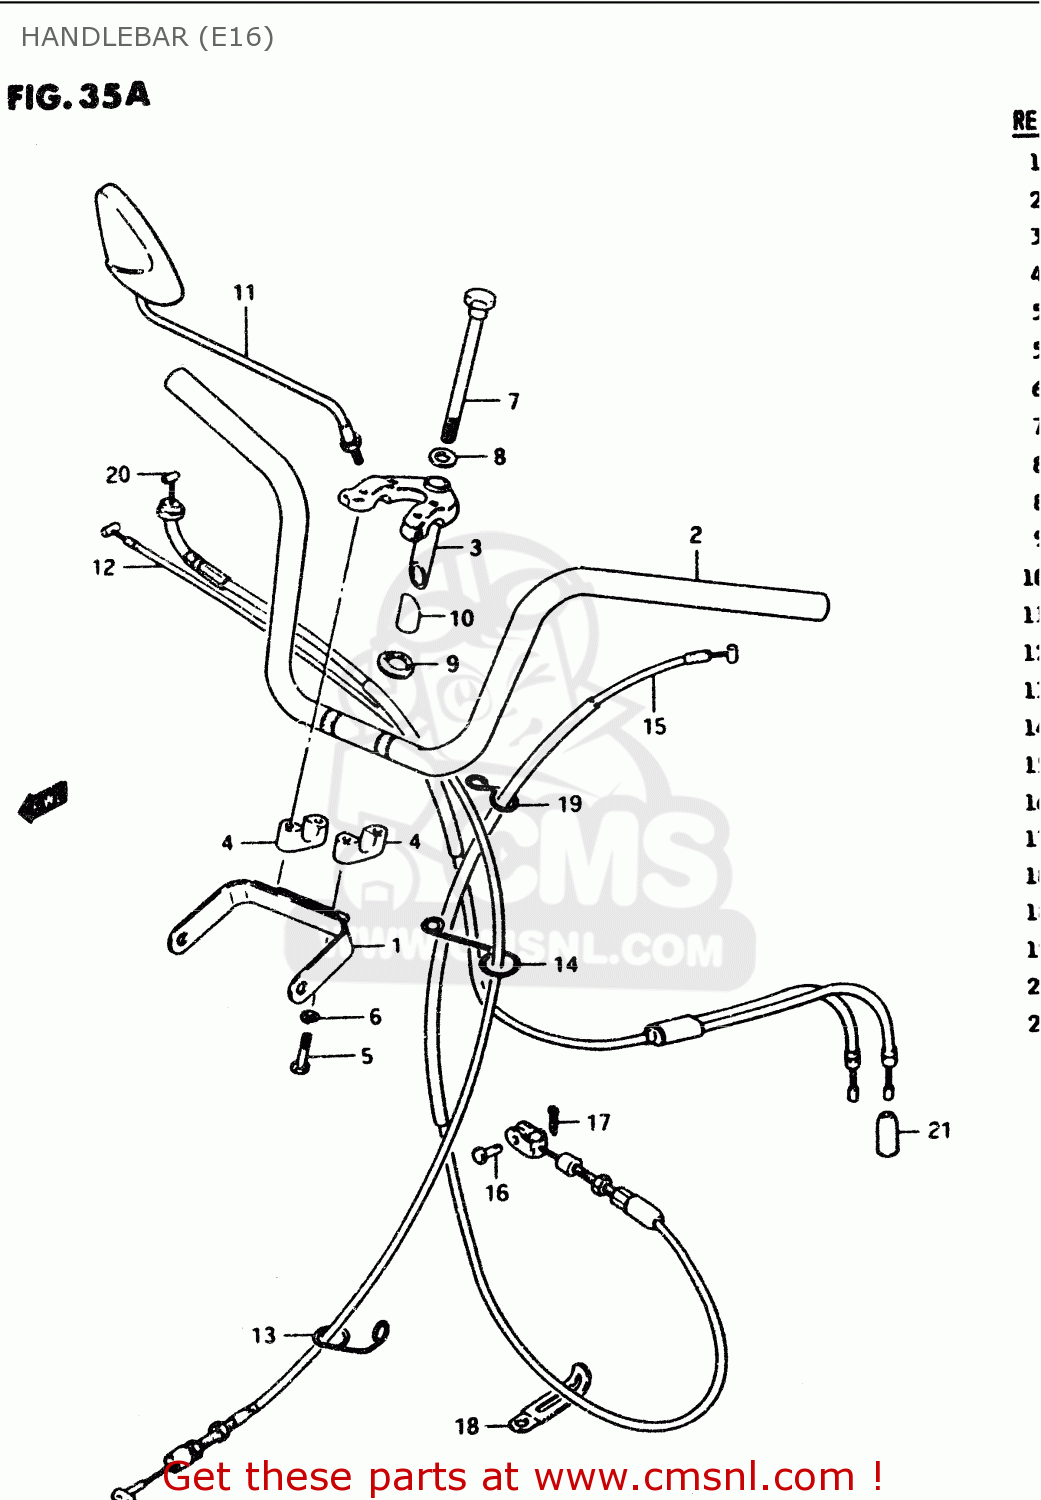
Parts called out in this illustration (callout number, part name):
1	BRACKET,HEAD LAMP HOUSING
2	HANDLEBAR
3	BRACKET,HANDLEBAR
4	HOLDER,HANDLE UPR
5	BOLT
6	WASHER,LOCK,8.
7	BOLT(12X114)
8	WASHER
9	STOPPER
10	STOP,HANDLE EXPANDER
11	MIRROR ASSY, REAR VIEW
12	CABLE,FR BRAKE
13	GUIDE, LOWER
14	GUIDE,FR BRAKE CABLE UPR
15	CABLE ASSY,CLUTCH
16	PIN(L:13)
17	PIN
18	CLAMP
19	GUIDE,CABLE
20	CABLE ASSY,THROTTLE
21	SEAL,DUST(7X18X30)
